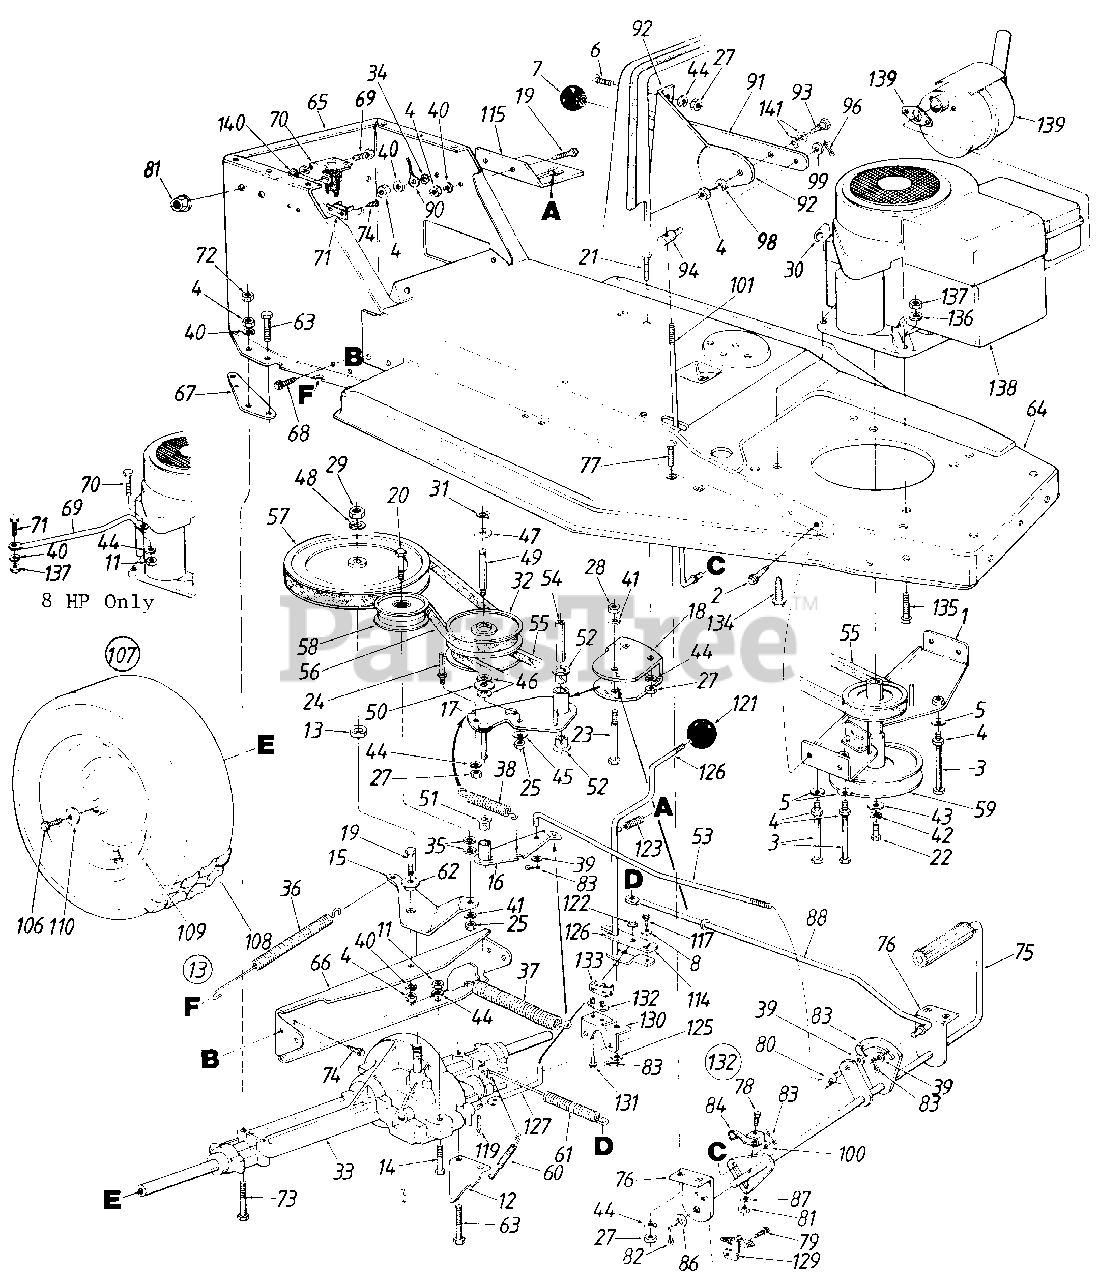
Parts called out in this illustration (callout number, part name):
1	Engine Pulley Belt Guard Ass'y.
2	Hex AB-Tap Scr. 1/4 x .62"
3	Hex Bolt 5/16-18 x 51/4" Lg.
4	Hex Nut 5/16-18 Thd.
5	Bell-Wash. .345" I.D. x .88
6	Truss-Mach. Scr. 1/4-20 x .50" Lg.
7	Gear Shift Knob
8	Bell-Wash. .265" I.D. x .75
11	Hex Nut 1/4-28 Thd.
12	Spring Retainer Brkt.
13	Spacer. 5" I.D.
14	Hex Bolt 1/4-28 x 1.75" Lg.
15	Idler Bracket
16	Variable Speed Torque Brkt. Ass'y.
17	Variable Speed Brkt. Ass'y.
18	Variable Speed Pivot Brkt.
19	Hex Bolt 5/16-18 x .75" Lg.
20	Hex Bolt 3/8-24 x 13/4" Lg. Gr. 5
21	Carr. Bolt 1/4-20 x .75" Lg.
22	Hex Bolt 7/16-20 x 1.5" Lg.
23	Hex Bolt 3/8-16 x 2.5" Lg.
24	Belt Guard Pin
25	Hex Nut 3/8-24 Thd.*
27	Hex Nut 1/4-20 Thd.
28	Hex Nut 3/8-16 Thd.
29	Hex Jam Nut 1/2-20 Thd.
30	Clamp
31	Snap Ring
32	Variable Speed Pulley Ass'y.
33	Transaxle Complete
34	Ext. L-Wash. 5/16" I.D.
36	Extension Spring 6.12" Lg.
37	Extension Spring 7.5" Lg.
38	Extension Spring 2.59" Lg.
39	Fl-Wash. .385" I.D. x .620"
40	L-Wash. 5/16" I.D.
41	L-Wash. 3/8" I.D.
42	L-Wash. 7/16" I.D.
43	Fl-Wash. .450" I.D. x 1.25"
44	L-Wash. 1/4" I.D.
45	Bell-Wash. .39" I.D. x 1.13"
46	Fl-Wash. .56" I.D. x 1.0" O.D.
47	Washer "Teflon" .565 I.D.
48	L-Wash. 1/2" I.D.
49	Shaft .56" Dia. x 3.875" Lg.
50	Thrust Brg. 1.25 O.D.
51	Flanged Nyliner Brg.
52	Nyliner Flanged Brg.
53	Speed Control Link
54	Spacer
55	V-Belt
56	V-Belt
57	1/2 V-Pulley .500" I.D. x 8.00"
58	Idler Pulley 3-1/8" Dia.
59	Dbl. Pulley 6.0" Dia. x 3.56"
60	Extension Spring 3.18" Lg.
61	Extension Spring 7.08" Lg.
62	Shld. Spacer. 500" Dia.
63	Hex Bolt 5/16-18 x 2.75" Lg.
64	Front Frame
65	Rear Frame
66	Transaxle Support Brkt.
69	Hex Bolt 1/4-20 x .62" Lg.
70	Solenoid
71	Circuit Breaker
72	Hex L-Nut 5/16-18 Thd.
73	Hex Bolt 5/16-18 x 3.0" Lg.
74	Truss Mach. B-Tap Scr. #10 x.50" Lg.
75	Clutch/Brake Pedal Ass'y.
76	Clutch/Brake Pedal Mounting Brkt.
77	Carr. Bolt 1/4-20 x .62" Lg.
78	Hex Bolt 1/4-20 x 1.0" Lg.
79	Hex TT-Tap Scr. 1/4-20 x .5"
80	Ferrule
81	Hex Sems Nut 1/4-20 Thd.
82	Cot-Pin 3/32" Dia. x 1.0" Lg.
83	Cot-Pin 3/32" Dia. x .75" Lg.
84	Switch Actuator
86	Fl-Wash. .635" I.D. x 1.0"
88	Brake Rod
90	Ground Wire 7.25" Lg.
91	Speed Control Lever
92	5 Speed Selector Brkt.
93	Shld Bolt .437" Dia. x .35" Lg.
94	Ferrule
96	Intern. Cot-Pin 5/16" Dia.
98	L-Wash. 5/16 I.D.
99	Fl-Wash. .344" I.D. x .62"
100	Fl-Wash. .25" I.D. x .62" O.D.
101	Speed Control Rod
106	Hex L-Bolt 5/16-24 x .75" Lg.
107	Rear Wheel Ass'y. Comp.
110	Bell-Wash. .345" I.D. x .88"
114	Shift Lever Adjusting Link
115	Shift Lever Spring Brkt.
117	Hex Bolt 1/4-20 x .50 Lg.
119	Intern. Cotter Pin
121	Ball Knob
122	Retaining Ring
123	Compression Spring 1.5" Lg.
125	Fl-Wash. .469" I.D. x .88"
126	Shift Rod Ass'y.
127	Shift Rod
129	Safety Switch
130	Shift Lever Support
131	Hex Wash. Hd. #8 x .50" Lg.
132	Insulator Nut Plate
133	Spring Switch
134	Hex Wash. Hd. Tap Scr. 3/8-16 x 1.25" Lg.
135	Hex Bolt 5/16-24 x 1-1/4" Lg. Grade 5
136	L-Wash. 5/16" I.D.
137	Hex Nut 5/16-24 Thd.
138	Engine
139	Muffler
140	Ext. L-Wash. 1/4" I.D.
141	Wave Wash. .445" I.D.
